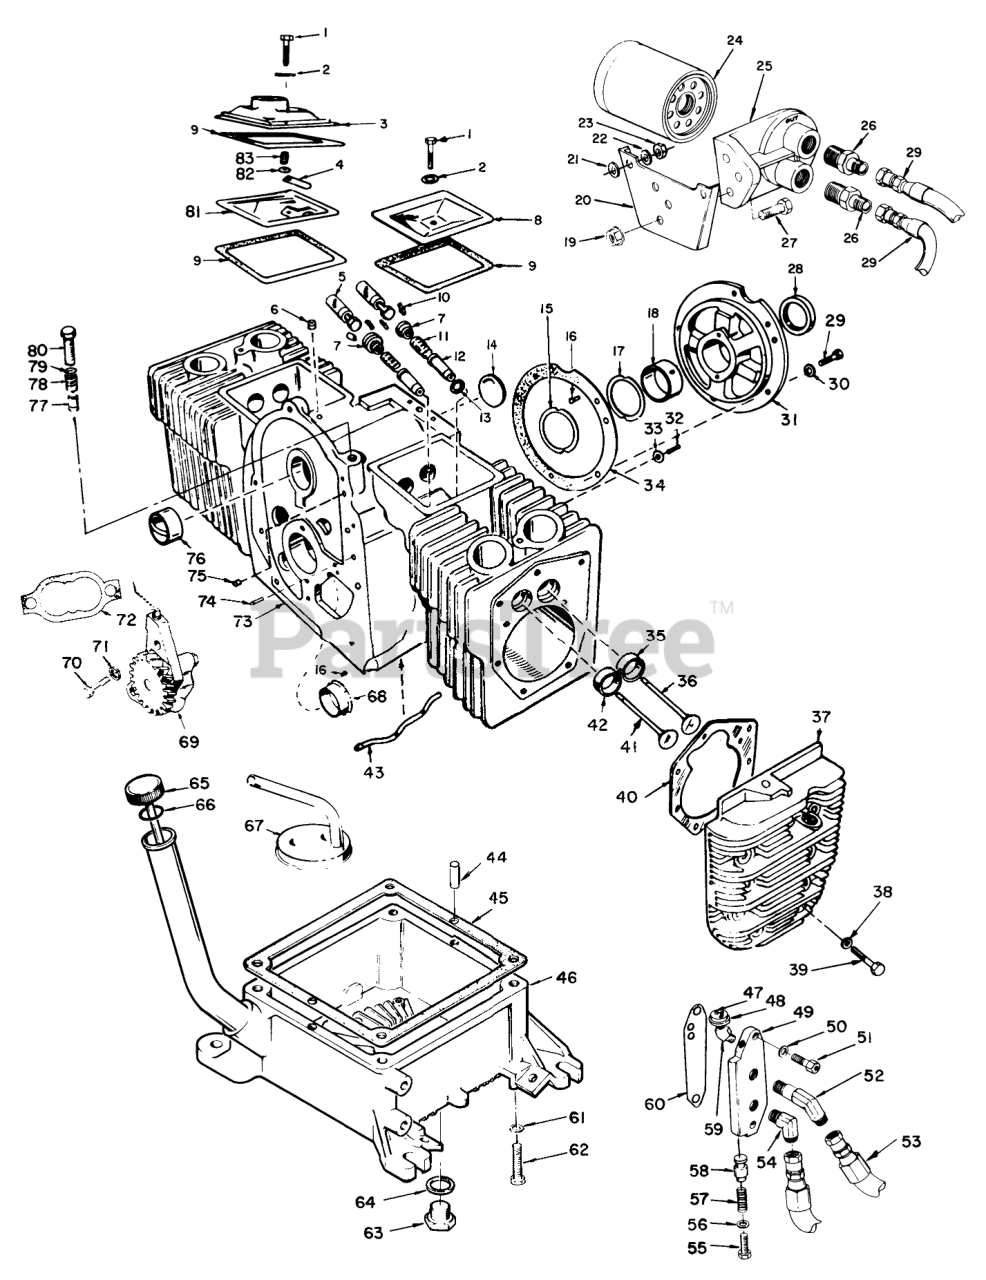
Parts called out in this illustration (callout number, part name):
1	Screw-Cap Hex Hd.
2	Washer, Flat-Copper
3	Cover-Valve
4	Reed-Breather Valve
5	Tappet, Valve (Standard)
6	Plug, Breather Hole
7	HYD MOTOR ASM
8	RH LEVER / GRIP ASM
9	Gasket, Valve Cover
10	Lock, Valve Spring
11	Spring Valve
12	Guide, Valve
13	Gasket, Intake Valve Guide
14	Plug, Welch-Camshaft Opening
15	Washer-Thrust
16	Pin, Drive-Bearing stop
17	Shim, Crankshaft End Play (.005)
18	Bearing, Crankshaft Rear Standard (Incl. Ref. #15)
19	Nut, Self-Lock
20	Bracket, Remote Oil Filter
21	Washer, Over Bracket
22	Washer, Under Bracket
23	Nut, Hex
24	Filter Oil
25	Base, Remote Oil Filter
26	Connector, Male
27	Screw Cap-Hex Hd.
28	Seal, Oil-Crankshaft Rear
29	Screw Cap-Hex Hd.
30	Washer, Lock-Spring
31	Plate, Bearing-Rear
33	Washer, Flat
34	Gasket, Bearing Plate
35	Insert, Valve Seat-Intake (Standard)
36	BRUSH-SCRAPER, WIDE (18 INCH)
37	LEVER-ACTUATING
38	Washer, Flat
39	Screw, Cap-Hex Head (Special)(5/16-18x 1-5/8")
40	SPACER
41	Valve Exhaust
42	GAS-LINE
43	Tube, Oil-Cylinder Block
44	Pin Dowel-Oil Base
45	Gasket, Oil Base
46	Base, Oil
47	Lead, Low Oil Pressure Cut Off
48	Switch, Low Oil Pressure Cut Off
49	Adapter, Oil Filter
50	Washer, Flat Copper
51	Screw, Cap-Socket Head
52	Elbow, Male (To Filter)
53	Hose, Oil
54	Elbow, Male (From Filter)
55	Screw, Cap Hex Hd.
56	Washer, Flat
57	Spring, By-Pass
58	Plunger, Bypass Valve
59	Elbow, Street 45 Deg.
60	Gasket, Oil Filter Adapter
61	Washer, Lock-Spring
62	Screw, Cap-Hex Head
63	Plug, Oil Drain
64	Gasket, Oil Drain
65	Cap and Indicator,Oil Fill
66	O-Ring, Oil Fill Cap
67	Cup, Intake-Oil Pump
68	Bearing, Crankshaft-Front(Flanged) Standard
69	Pump, Oil
70	Screw, Cap-Hex Hd.
71	Washer, Lock
72	Gasket Kit, Oil Pump
73	Block Assy. (Incl. Ref. #6, 12-18, 29-31, 34-35, 42-43, 68, 74 & 76)
74	Pin, Gear Cover Alignment
75	Plug, Core Hole
76	Bearing, Camshaft
77	Plunger, Bypass Valve
78	Spring, By-Pass
79	Washer, Flat
80	Screw, Cap-Hex Head
81	Baffle, Breather Valve
82	Washer, Flat
83	Spring, Breather Valve
